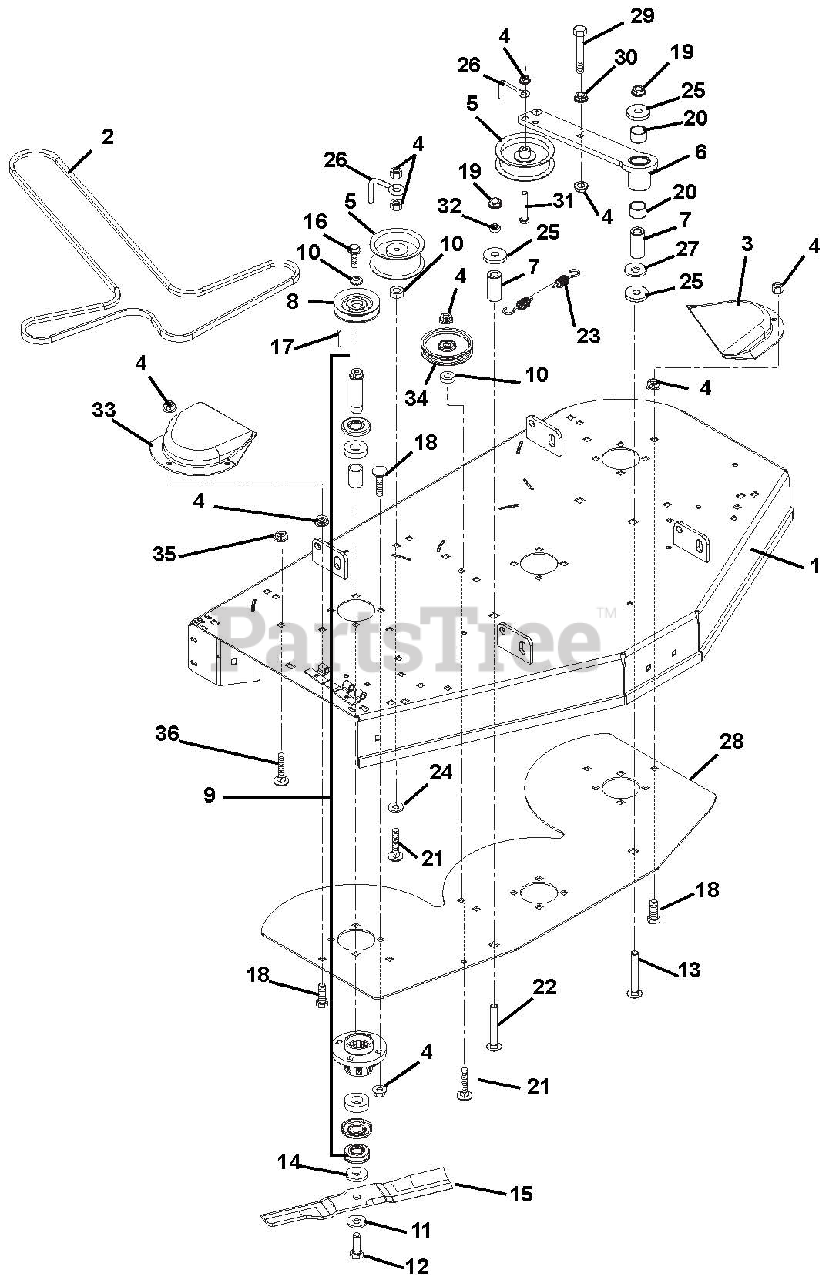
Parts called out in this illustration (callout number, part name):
1	WMT,40"DECK
2	V-BELT, HA-WRAPPED
4	@NUT-LK-NYL-FLG .38-16 YWZC
5	PULLEY, IDLER 4.00
6	WMT, IDLER PIVOT ARM
7	BSHG, SPCR .502X.997X2.03 PM
8	SHEAVE, SPINDLE - 4.00 DIA.
9	ASSEMBLY, SPINDLE
10	WSHR,FLT STL.406X1.50X.245YWZC
11	WSHR-BLVL .669X1.535X.138
12	BLT-HEX .62-18X1.75 GR8 YWZC
13	@BLT-RDHDSQNK .50-13X3.50 G5YZ
14	@WSHR-FL-STL.688X1.75X.134 YWZ
15	MOWER BLADE, 13.94"
16	BLT-HEX .38-16X1.00 YZ GR8
17	KEY, SQ .25 X .38 X .25
18	@BLT-RDHDSQNK .38-16X1.25 G5YZ
19	@NUT-LK-TOP-FLG .50-13 YWZC
20	BRG, 1.00 X 1.12 X .75
21	@BLT-RDHDSQNK .38-16X2.00 G5YZ
22	@BLT-RDHDSQNK .50-13X3.75 G5YZ
23	SG-TENS .187X1.50X9.94 WLD 40
24	@WSHR-FL-STL.531X1.06X.095YWZC
25	WSHR-FL-STL .515X1.625X.250 YZ
26	BELT FINGER
27	WSHR-FL-STL.511X1.441X.125 YWZ
28	PLATE,40"DOUBLER
29	@BLT-HEX .38-16X2.00 GR5 YWZC
30	@NUT-SPNLK-FLG .375-16 YWZC
31	@BLT-HEX .38-16X2.50 GR5 YWZC
32	NUT-SPNLK-FLG .50-13 YWZC
33	BELT COVER
34	IDLER, FLAT .38X4.00X1.06
35	@NUT-LK-NYL-FLG .31-18 YWZC
36	@BLT-RHDSSQNK .31-18X.62 G5YZ
